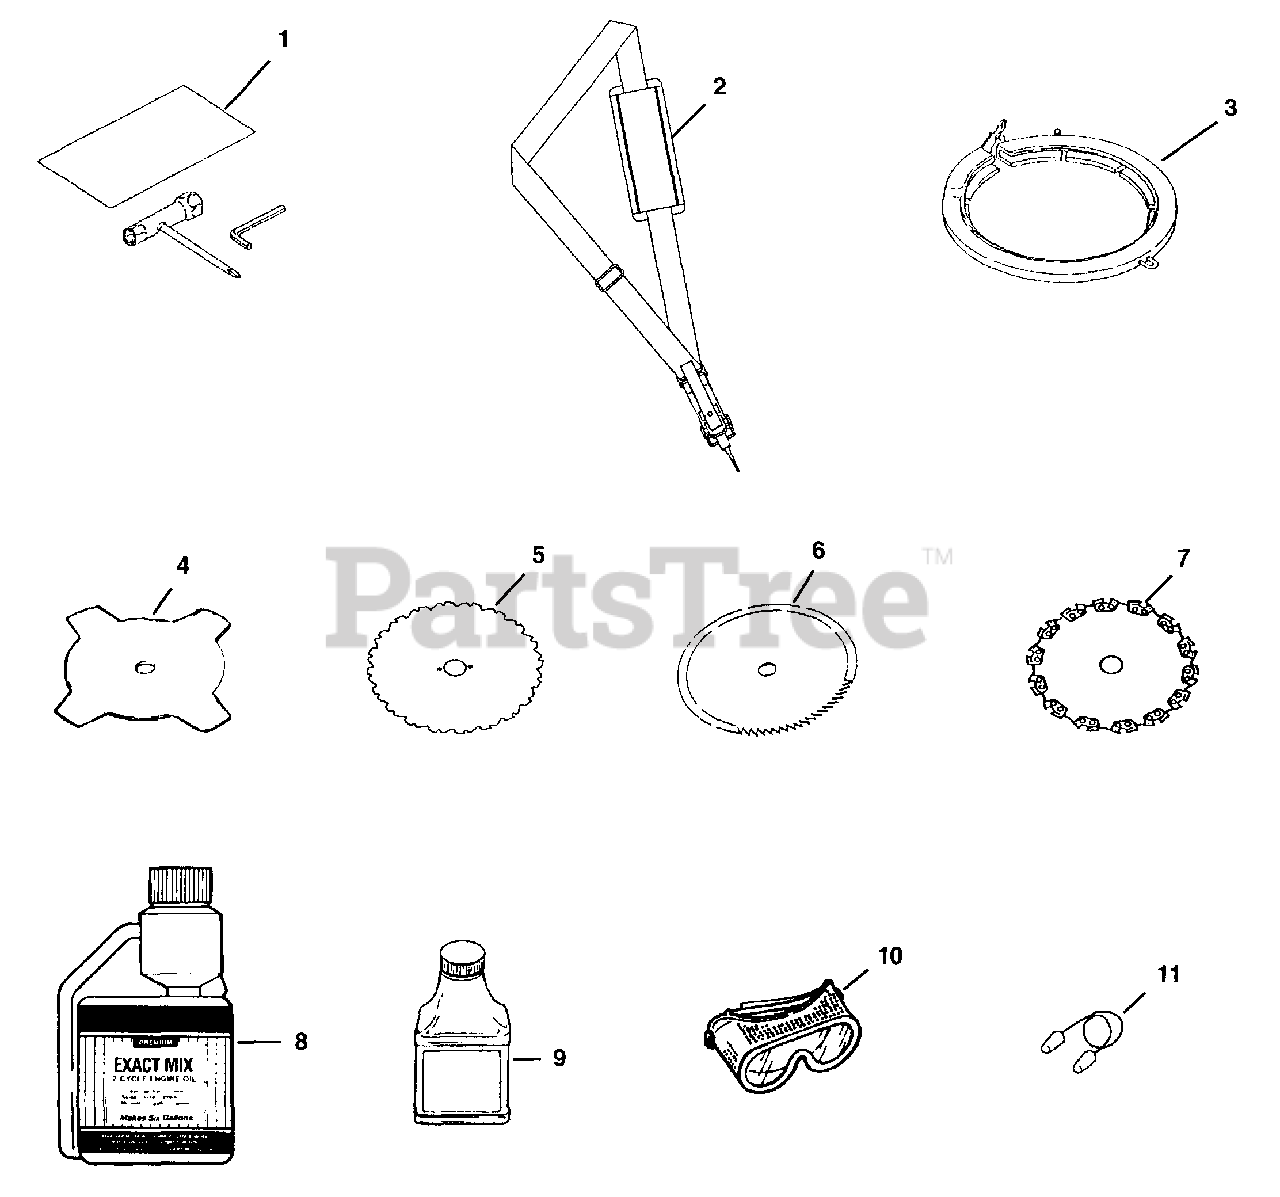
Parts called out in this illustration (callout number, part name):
1	TOOL KIT
3	BLADE COVER
4	QUAD BLADE
5	XRT BLADE
6	SAW BLADE
7	MACHETTE BLADE
8	EXACT MIX (TM) (16 oz.)
9	EXACT MIX (TM) (26 oz.)
11	EAR PLUGS
12	DECAL KIT
